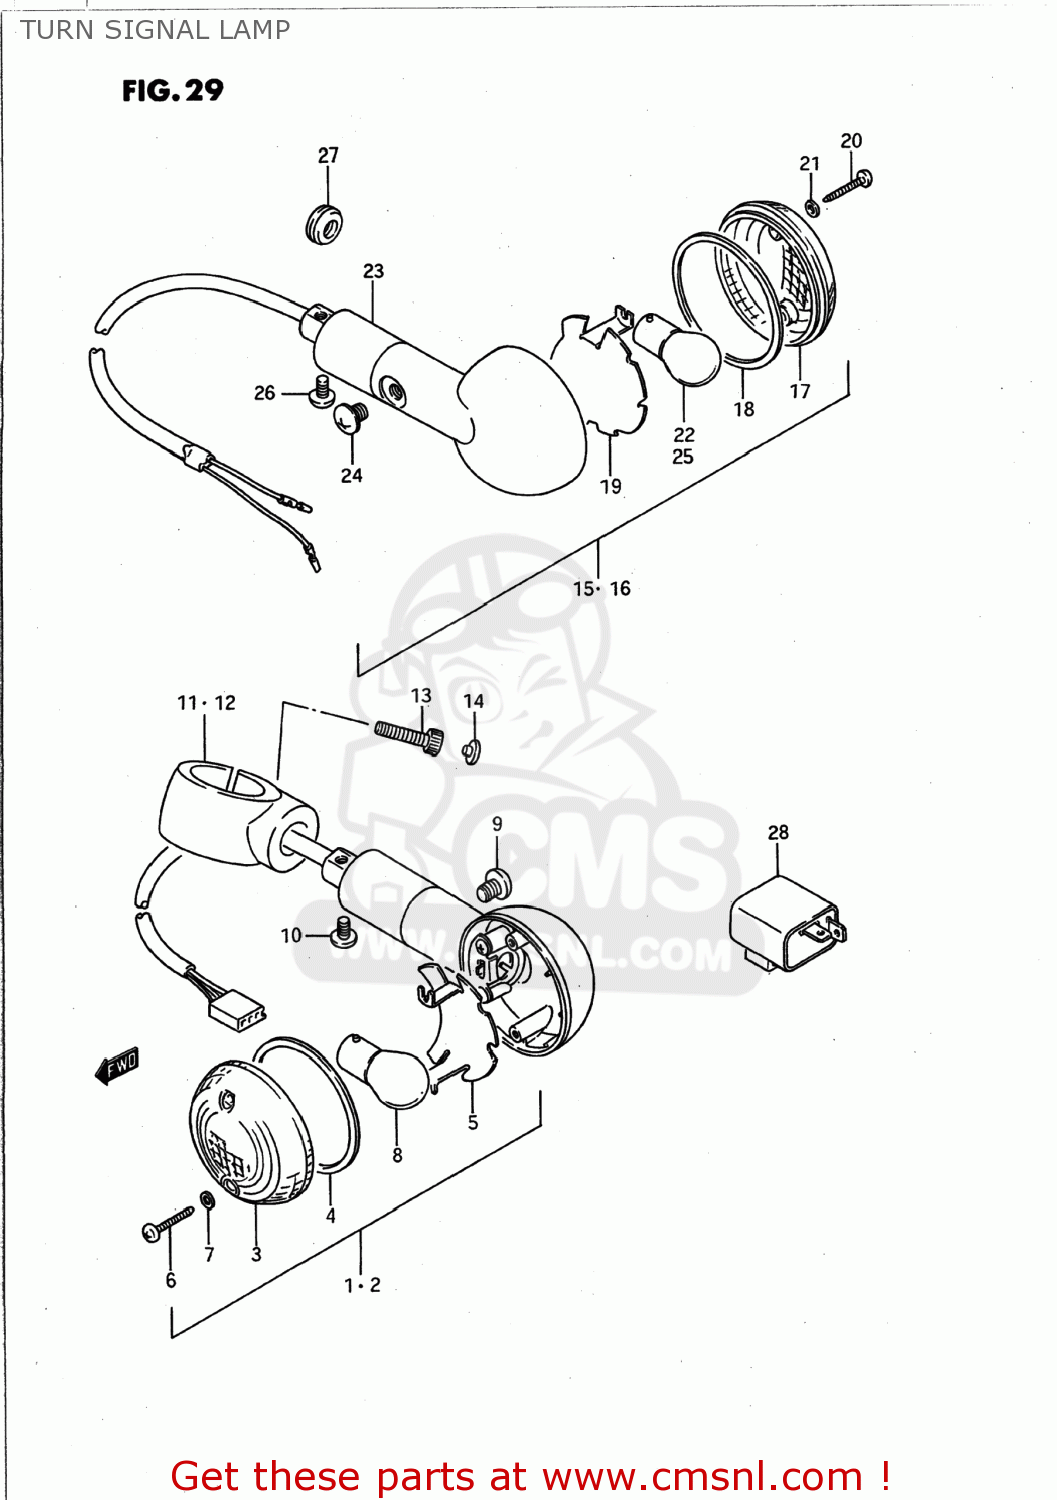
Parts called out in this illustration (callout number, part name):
1	LAMP ASSEMBLY,FRONT TURN SIGNAL
2	LAMP ASSEMBLY,FRONT TURN SIGNAL
3	LENS
4	GASKET (NAS)
5	REFLECTOR
6	SCREW
7	GASKET (NAS)
8	BULB(12V23/8W,TOKAI DENSO)
9	SCREW
10	SCREW
11	BRACKET,FR TURNSIGNAL LAMP,R
12	BRACKET,FR TURNSIGNAL LAMP,L
13	BOLT
14	CAP(OD:10)
15	LAMP ASSEMBLY,REAR TURN SIGNAL
16	LAMP ASSEMBLY,REAR TURN SIGNAL
17	LENS
18	GASKET (NAS)
19	REFLECTOR
20	SCREW
21	GASKET (NAS)
22	BULB 12V 21W
23	STAY,TURNSIGNAL LAMP
24	SCREW
25	BULB 12V 21W
26	SCREW
27	GROMMET
28	RELAY,TURN SIGNAL
